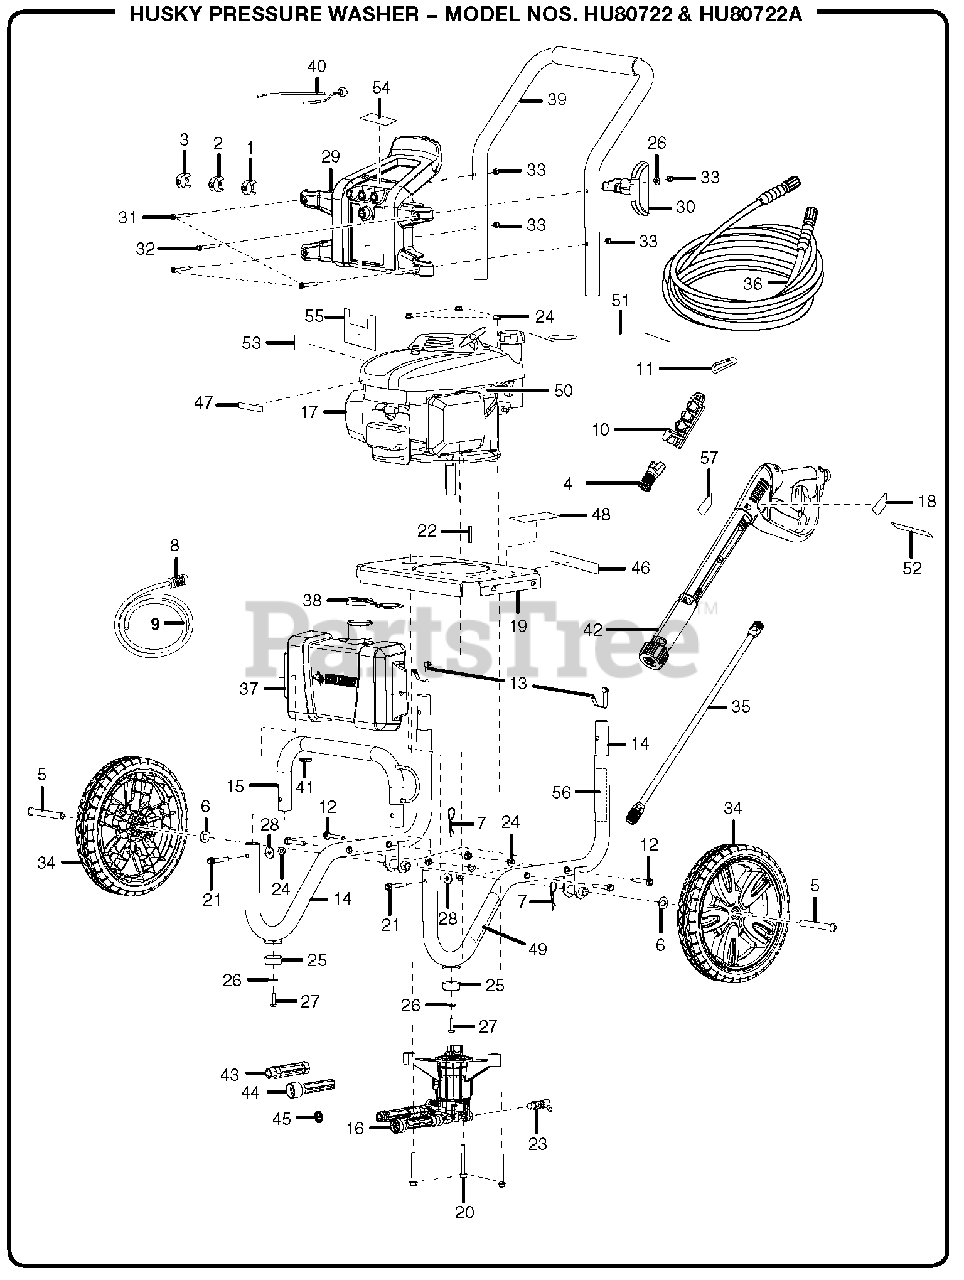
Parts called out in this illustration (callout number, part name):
1	0deg Nozzle
2	15deg Nozzle
2	40deg Nozzle
3	25deg Nozzle
4	Soap Blaster Nozzle
5	Axle
6	Washer (1/2 in.)
7	Hitch Pin
9	Injection Hose
10	Storage Holder (4 Nozzle)
11	Spring Clip
12	Bolt w/Washer (M8 x 55 mm Hex Hd.)
13	Lock Button w/Spring Clip
14	Main Frame Assembly
15	Front Frame
16	Pump
17	Engine (Honda)
18	Trigger Handle Logo Label
19	Engine Plate
20	Bolt (M8 x 65 mm)
21	Bolt (M8 x 50 mm)
22	Output Shaft Key
23	Thermal Release Valve
24	Lock Nut (M8 x 1-1/4 in.)
26	Washer (1/4 in.)
27	Bolt (1/4-20 x 1 mm Hex Hd.)
28	Washer (5/16 in.)
29	Hose and Nozzle Holder
30	Wand Holder
31	Screw (1/4-20 x 1.85 in., Torx)
32	Screw (1/4-20 x 2.27 in., Torx)
33	Lock Nut (1/4-20)
34	Wheel (12 in. x 2 in.)
35	Spray Wand
36	High Pressure Hose
37	Soap Tank
38	Soap Tank Cap
39	Handle Assembly
40	Bungee Cord and Bead Assembly
41	Injection Hose Holder
42	Trigger Handle Assembly
43	Outlet Tube
44	Inlet Tube
45	Filter Screen
46	Data Label
47	Honda Logo Label
48	Warning Label
49	Pump Quick Start Label
50	Fuel Valve Label
51	Engine Oil Fill (Hang Tag)
52	Wand Label (Max Rating)
53	Hot Muffler Label
54	Nozzle Label
55	Performance Label
56	Engine Quick Start Label
57	Trigger Handle Warning Label
